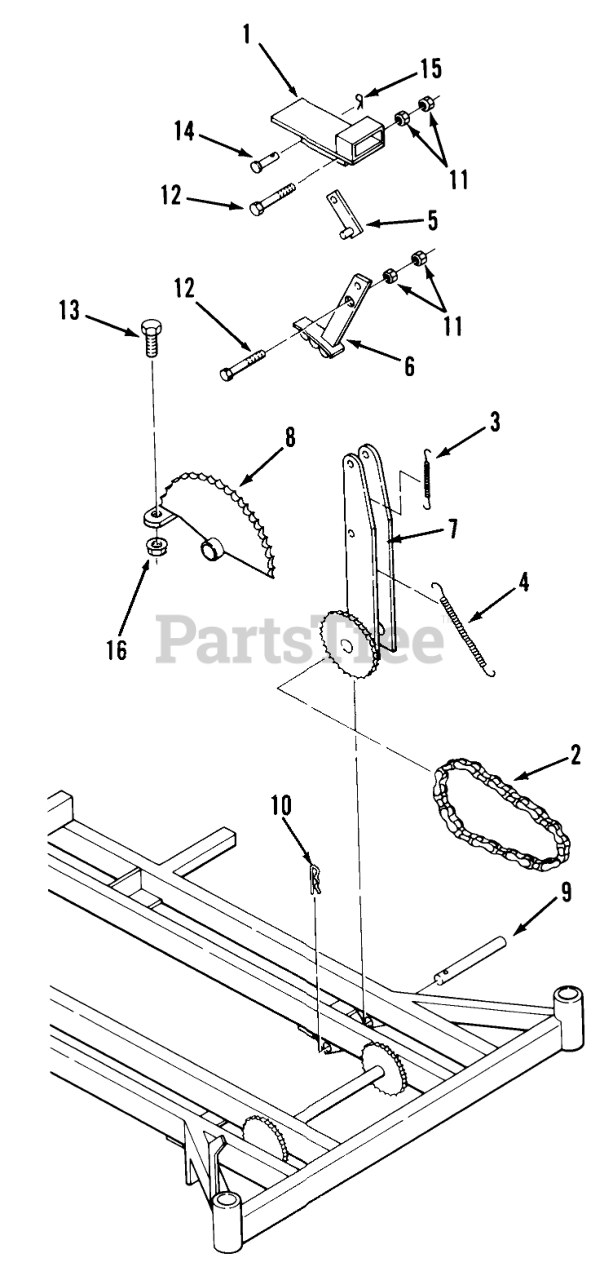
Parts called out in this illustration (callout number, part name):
1	Foot Pedal
2	Foot Pedal Chain
3	Foot Spring-Short
4	Extension Spring
5	Pivot Link
6	Lift Arm Pawl
7	Lever Arm and Sprocket Assembly
8	Height Control Sprocket
9	Pin
10	Hairpin
11	Nut
12	Hex Bolt 5/16-18 x 1 1/2
13	Bolt
14	PIN CLEVIS 5/16X1
15	HAIRPIN
16	Flanged Nut
